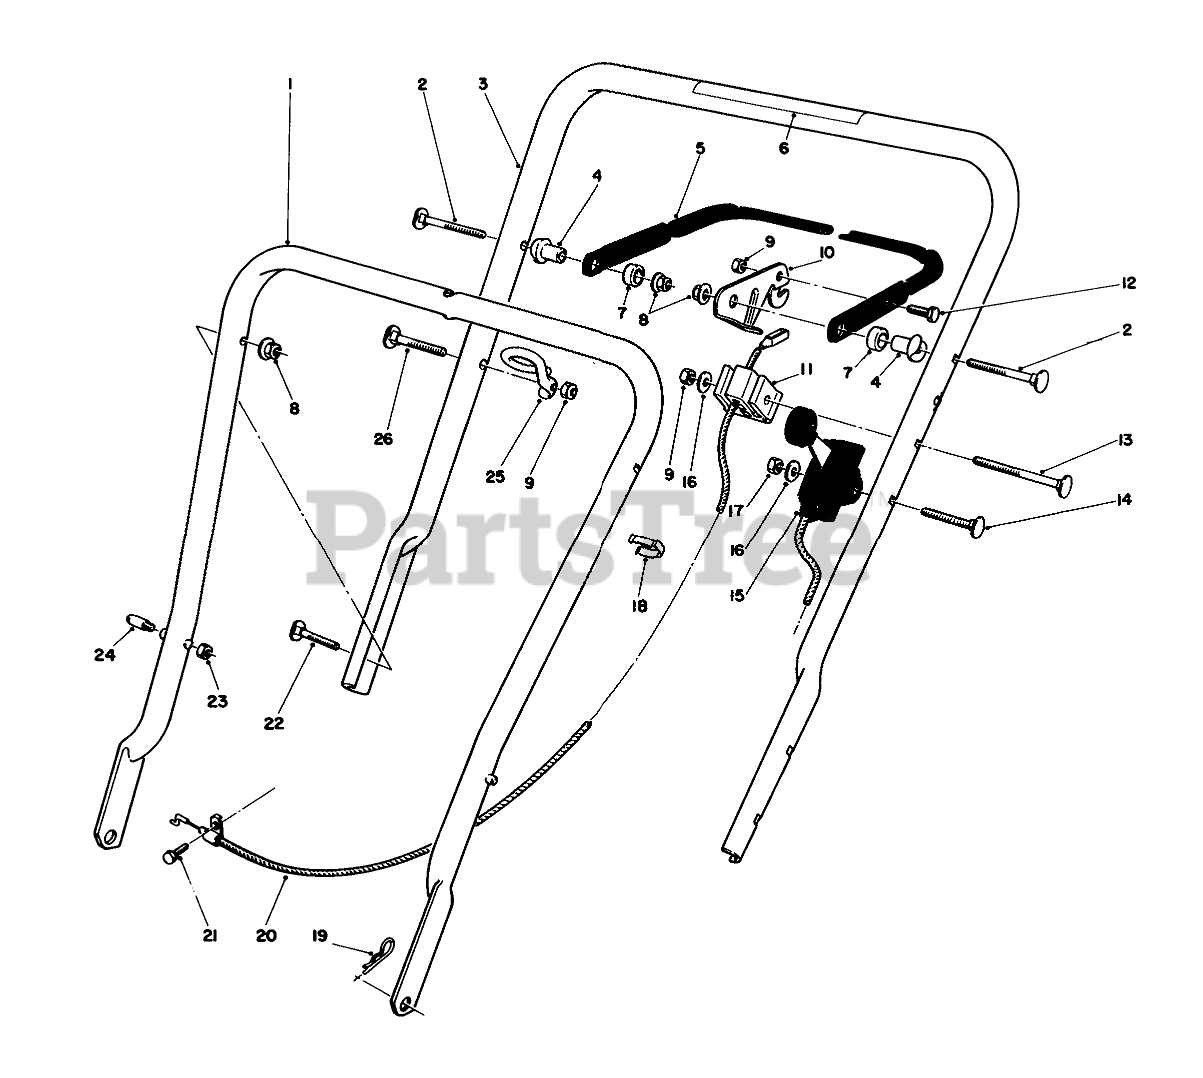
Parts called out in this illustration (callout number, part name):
1	LOWER HANDLE ASM
1	BAG REPLACMNT44-0540
2	5/16-18 X 2 HNDLE SCREW
2	BAG ROD
3	Handle-Upper (Incl. Ref. #6)
3	Grass Chute (Incl. Ref. #4 & 6)
4	SPACER-SUPPORT
4	RIVET 3/16 X 7/16
5	Bar-Control
5	BAG CHUTE DECAL
6	DECAL - HANDLE
6	Handle Chute
7	SPACER-NYLON
8	NUT-LOCK, NI
10	LEVER-CONTROL
11	SUPPORT-CABLE
12	SCREW-HH
13	HANDLE SCREW
14	SCREW-HANDLE
15	THROTTLE CONTROL
16	WASHER-FLAT
17	NUT-LOCK, NI
18	BOWDEN CLIP
19	PIN-COTTER, HAIR
20	BRAKE CABLE
21	SCREW-HH
22	SCREW
23	NUT-LOCK, NI
24	HANDLE PIN
25	Guide
26	HANDLE SCREW
